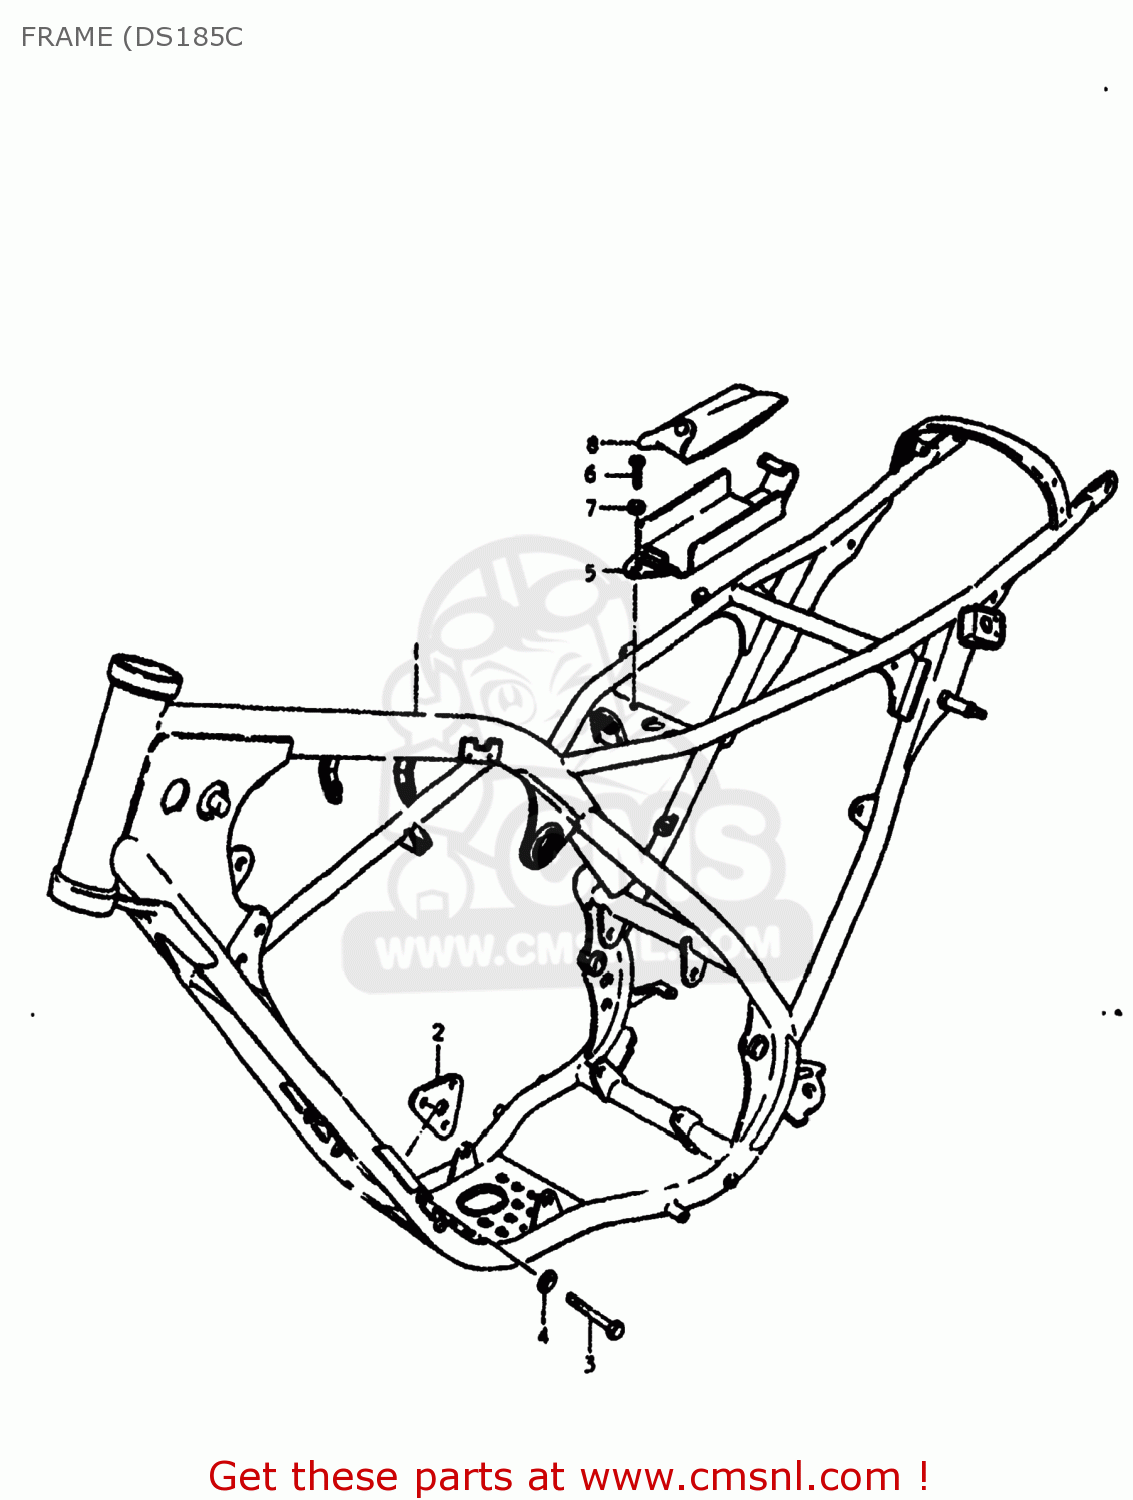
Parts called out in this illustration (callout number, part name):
1	FRAME
2	PLATE,ENG MTG,L
3	BOLT 8X55
4	WASHER
5	HOLDER,TOOL
6	SCREW
7	WASHER
8	TOOL ASSY
